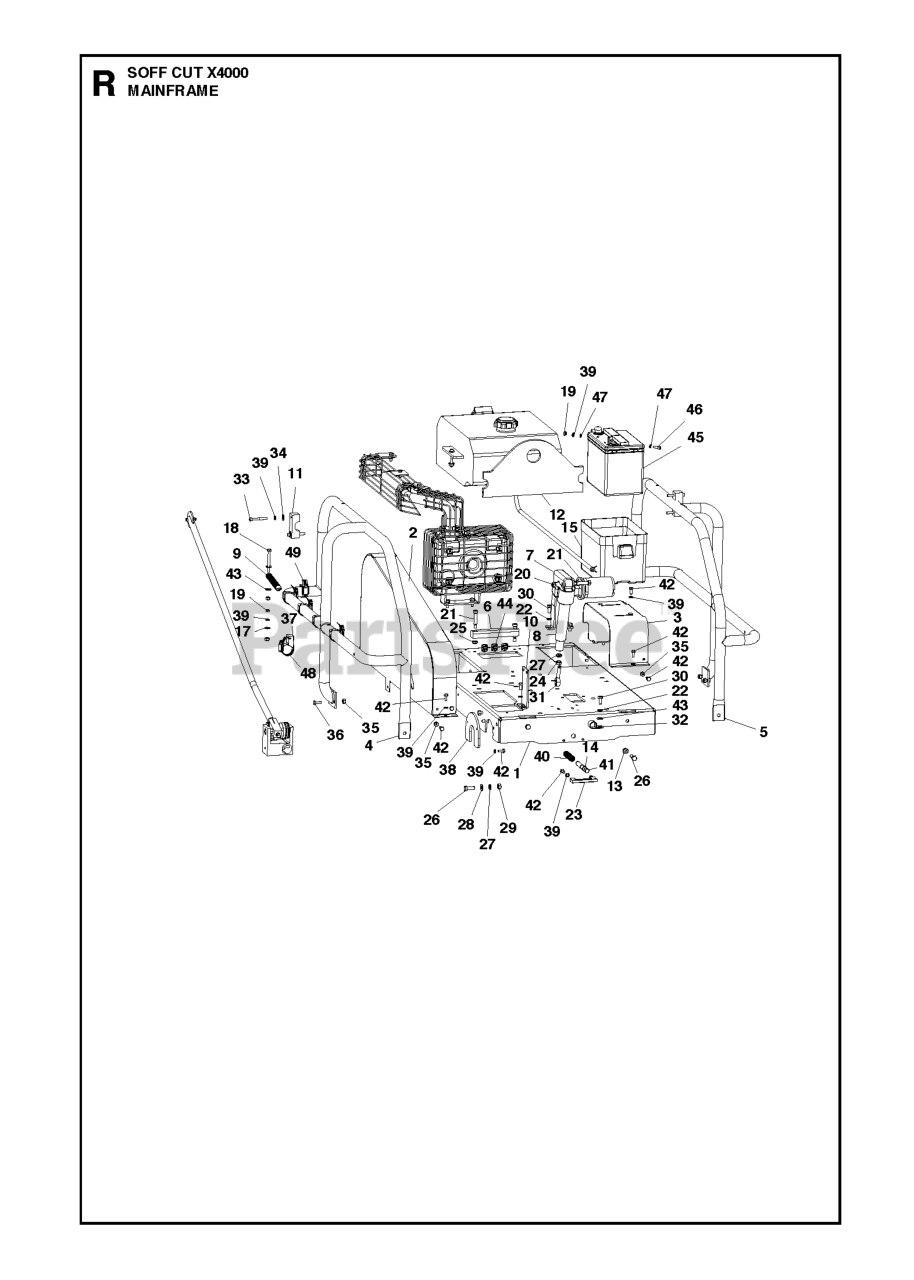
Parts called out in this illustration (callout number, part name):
7	ACTUATOR BRACKET
13	NUT
20	NUT
30	SCREW
34	FLAT WASH 1/4 PFC9 SAE ZINC
35	NYLOC NUT 1/4-20 CAD PL.
43	WASHER
